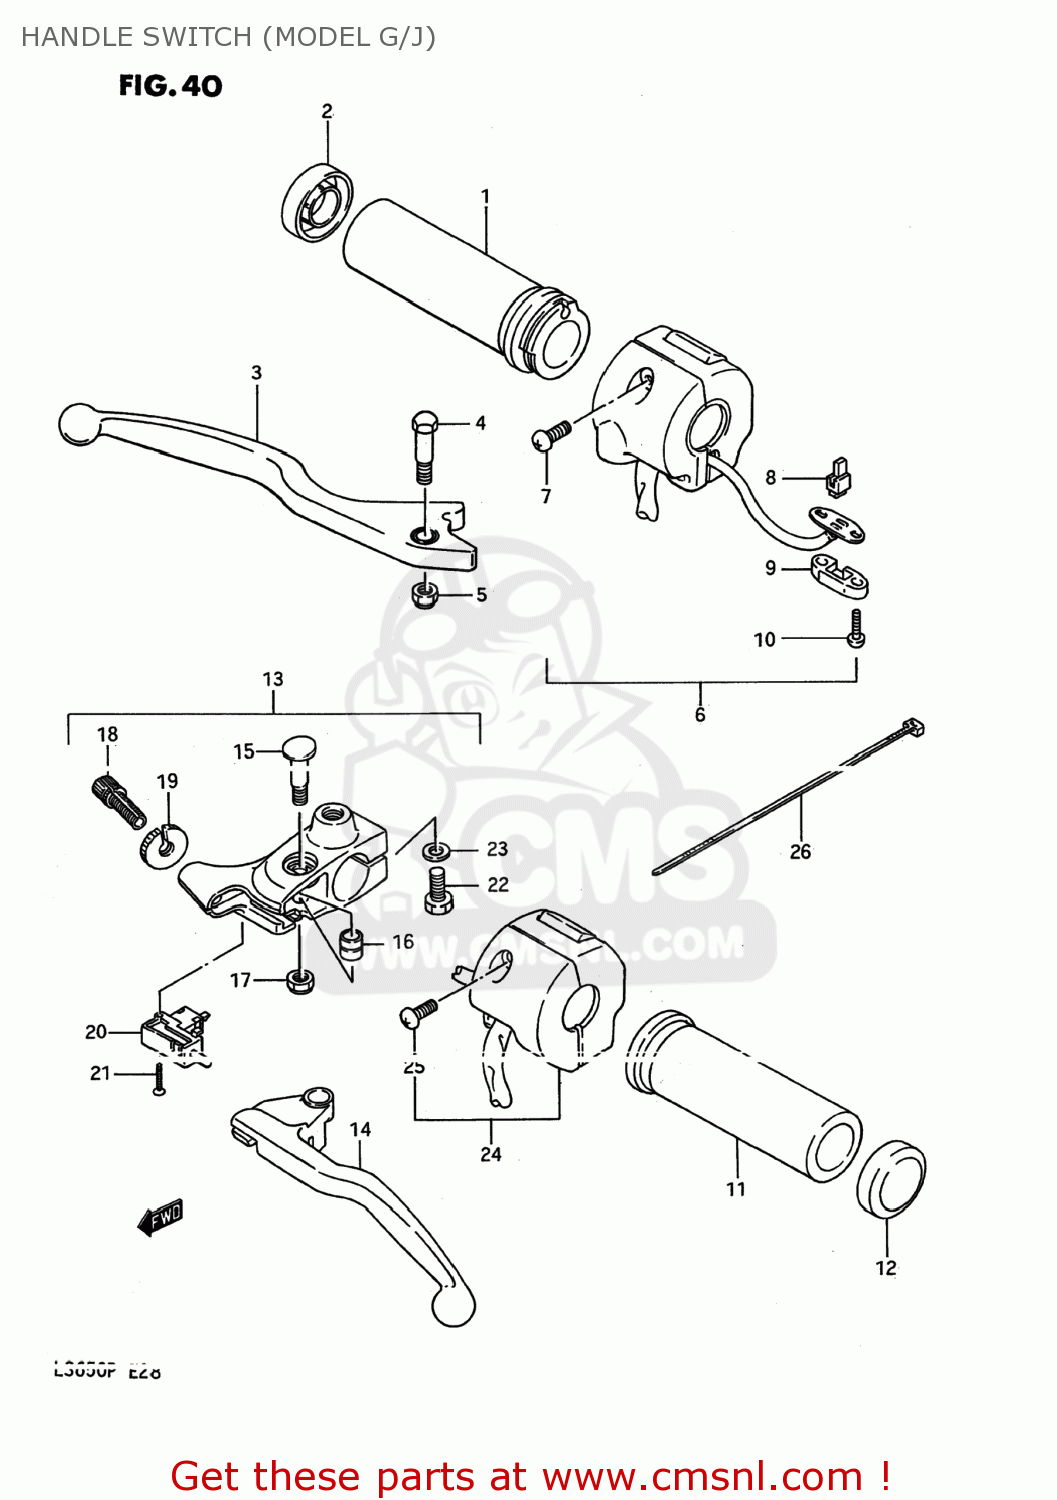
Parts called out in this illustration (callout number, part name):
1	GRIP,THROTTLE
2	CAP,GRIP END
3	LEVER,BRAKE
4	BOLT,LEVER
5	NUT 6MM
6	SWITCH ASSEMBLY,HANDLE,LEFT
7	SCREW
8	CONTACT,SWITCH
9	COVER,BRAKE SWITCH
10	SCREW
11	GRIP,L
12	CAP,GRIP END
13	LEVER ASSEMBLY
14	LEVER,CLUTCH
15	BOLT,CLUTCH LEVER
16	SPACER,CLUTCH LEVER PIVOT
17	NUT 6MM
18	ADJUSTER,WIRE
19	NUT,LOCK
20	SWITCH,CLUTCH
21	SCREW
22	BOLT
23	WASHER
24	SWITCH ASSY,HANDLE,L
25	SCREW
26	CLAMP
